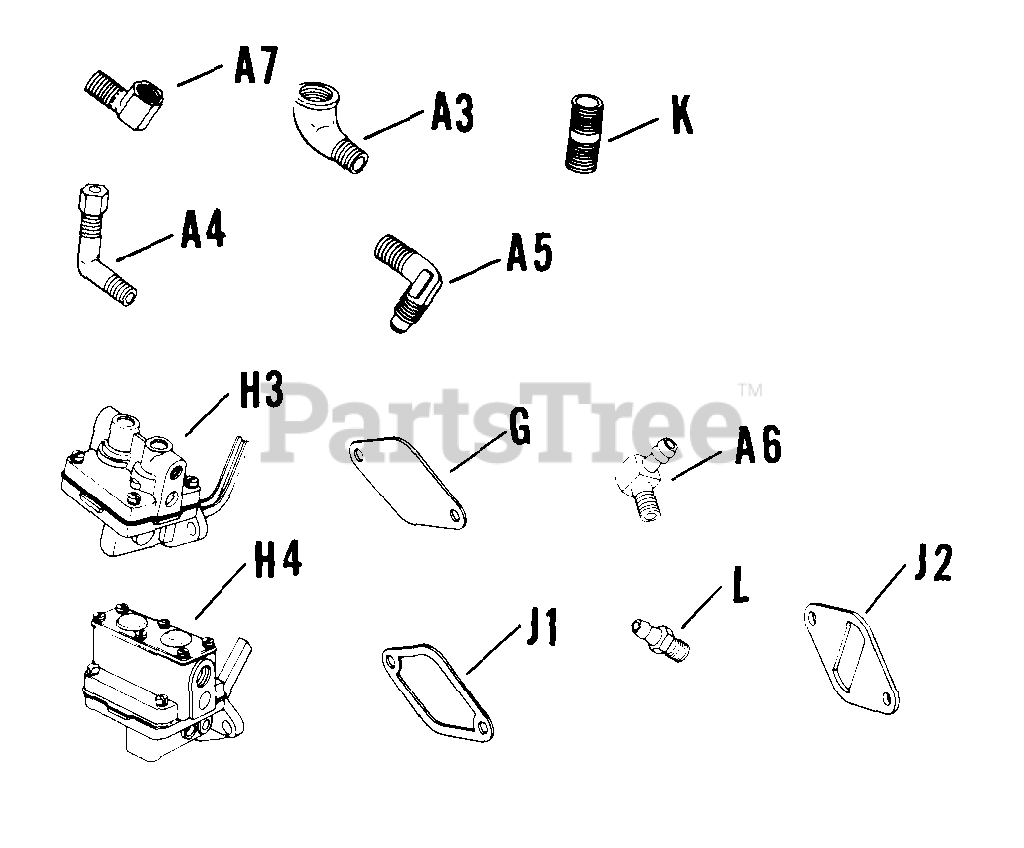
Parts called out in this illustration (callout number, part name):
A3	ELBOW - USE 48 283 03
A6	HOSE - USE 25 155 02
J1	GASKET - USE 25 041 05
K	PIPE - USE 47 136 02
